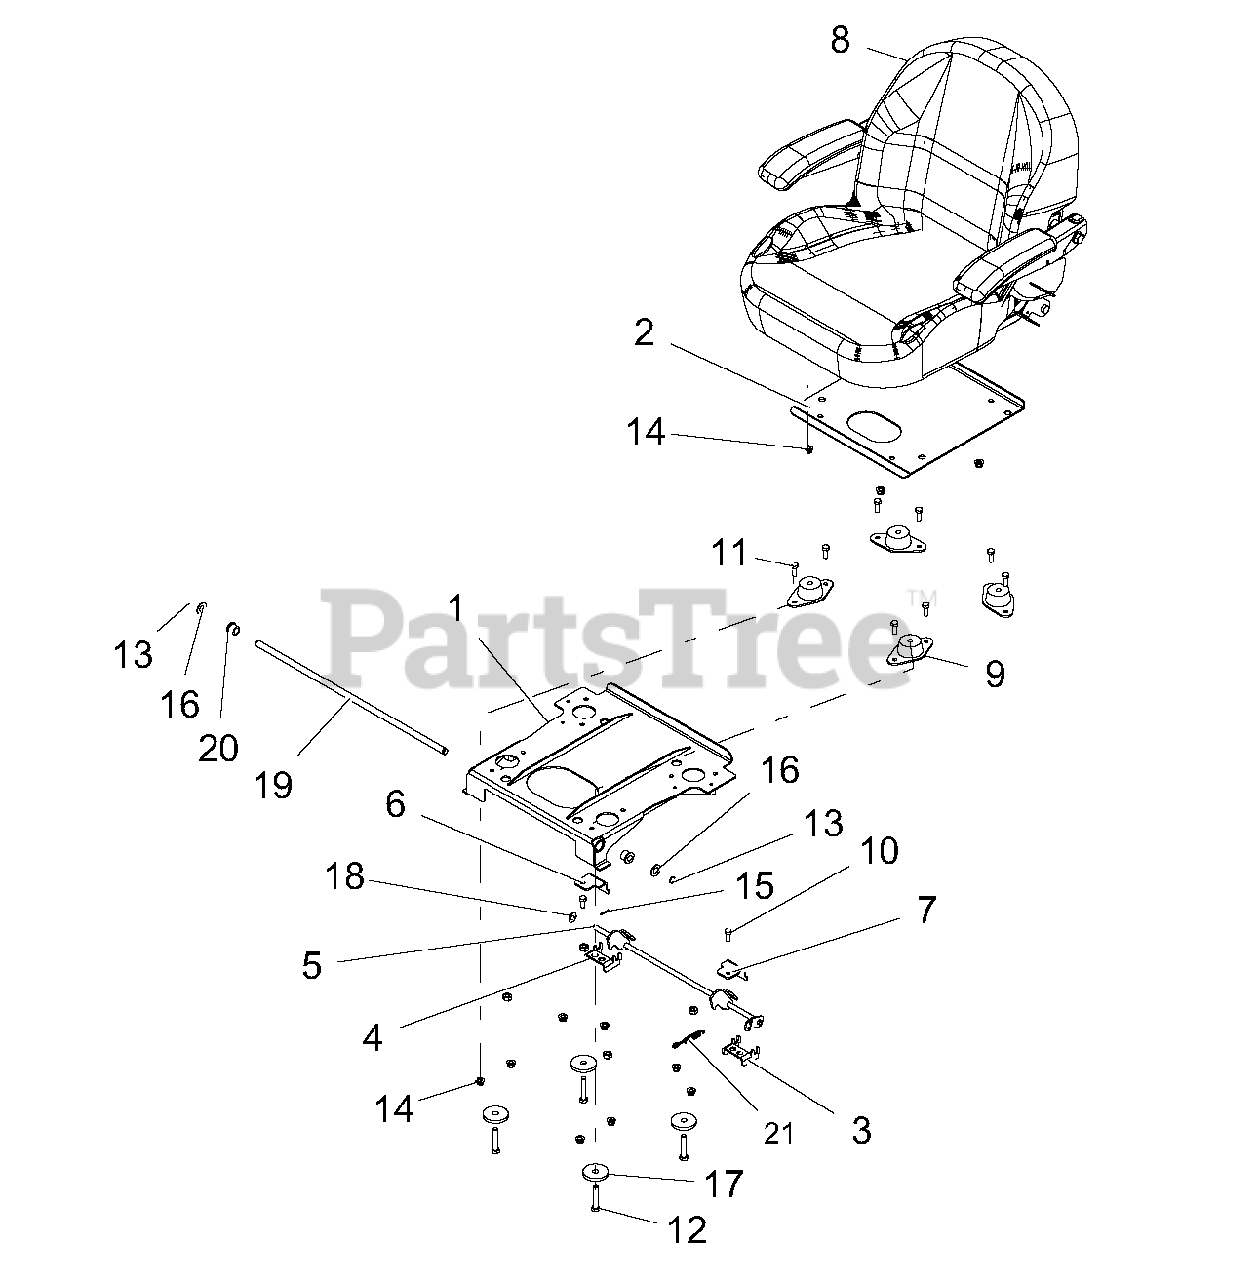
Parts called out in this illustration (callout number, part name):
1	WLDMT, PT ISOLATOR MTG PLATE-BLACK
2	WLDMT, SEAT MOUNTING PLATE-BLACK
3	WLDMT, PT/PT100 LH SEAT LATCH MOUNT-BLACK
4	WLDMT, PT/PT100 RH SEAT LATCH MOUNT-BLACK
5	WLDMT, PRO-TURN SEAT LATCH-BLACK
6	RH TOP SEAT LATCH MOUNT
7	LH TOP SEAT LATCH MOUNT
8	SEAT, NON-SUSPENSION
9	MOUNT, FAIL-SAFE COMPRESSION
10	BLT-HEX .31-18X.75 GR5 YWZC
11	BLT-HEX .31-18X.875 GR5 YWZC
12	BLT-HEX .38-16X2.00 GR5 YWZC
13	RG-RTNG-EXT .500x.050
14	NUT-LK-NYL-FLG .31-18 YWZC
15	@PIN-CTR .09X.75 EXTPRSQCT YWZ
16	WSHR-FL-STL .531X1.000X.063 YWZC
17	WSHR-FL-STL .469X2.00X.25 YWZC
18	WSHR-FL-STL.406X.812X.065 YWZ
19	SHAFT, PT/PT100 SEAT PIVOT
20	BSHG, SHLDR EP .358-16X.30 HEX YZ
21	SPRG, EXTENSION
